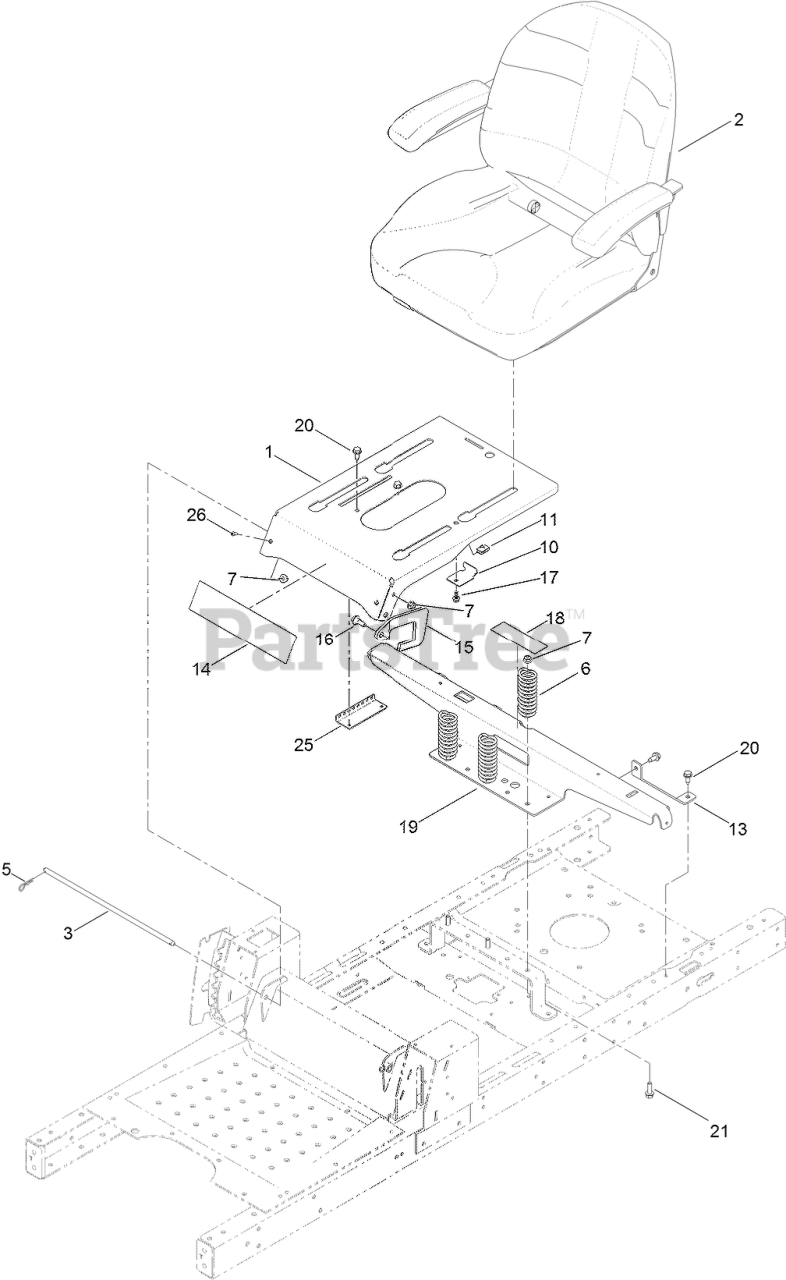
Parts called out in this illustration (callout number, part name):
1	PAN-SEAT
2	SEAT ASM
3	ROD-PIVOT, NARROW
5	PIN-COTTER
6	SPRING-COMPRESSION
7	NUT-HF, NI
10	BRACKET-STOP, SEAT
13	SUPPORT-TANK, REAR
14	DECAL-TIMECUTTER
15	PLATE-STOP
16	SCREW-SHOULDER
17	SCREW-HHF
18	DECAL-SERVICE, CE
19	SUPPORT-POD
20	SCREW-HWHTF
21	SCREW-HHF
25	BRACKET-LATCH, SEAT
26	SCREW-HSBH
